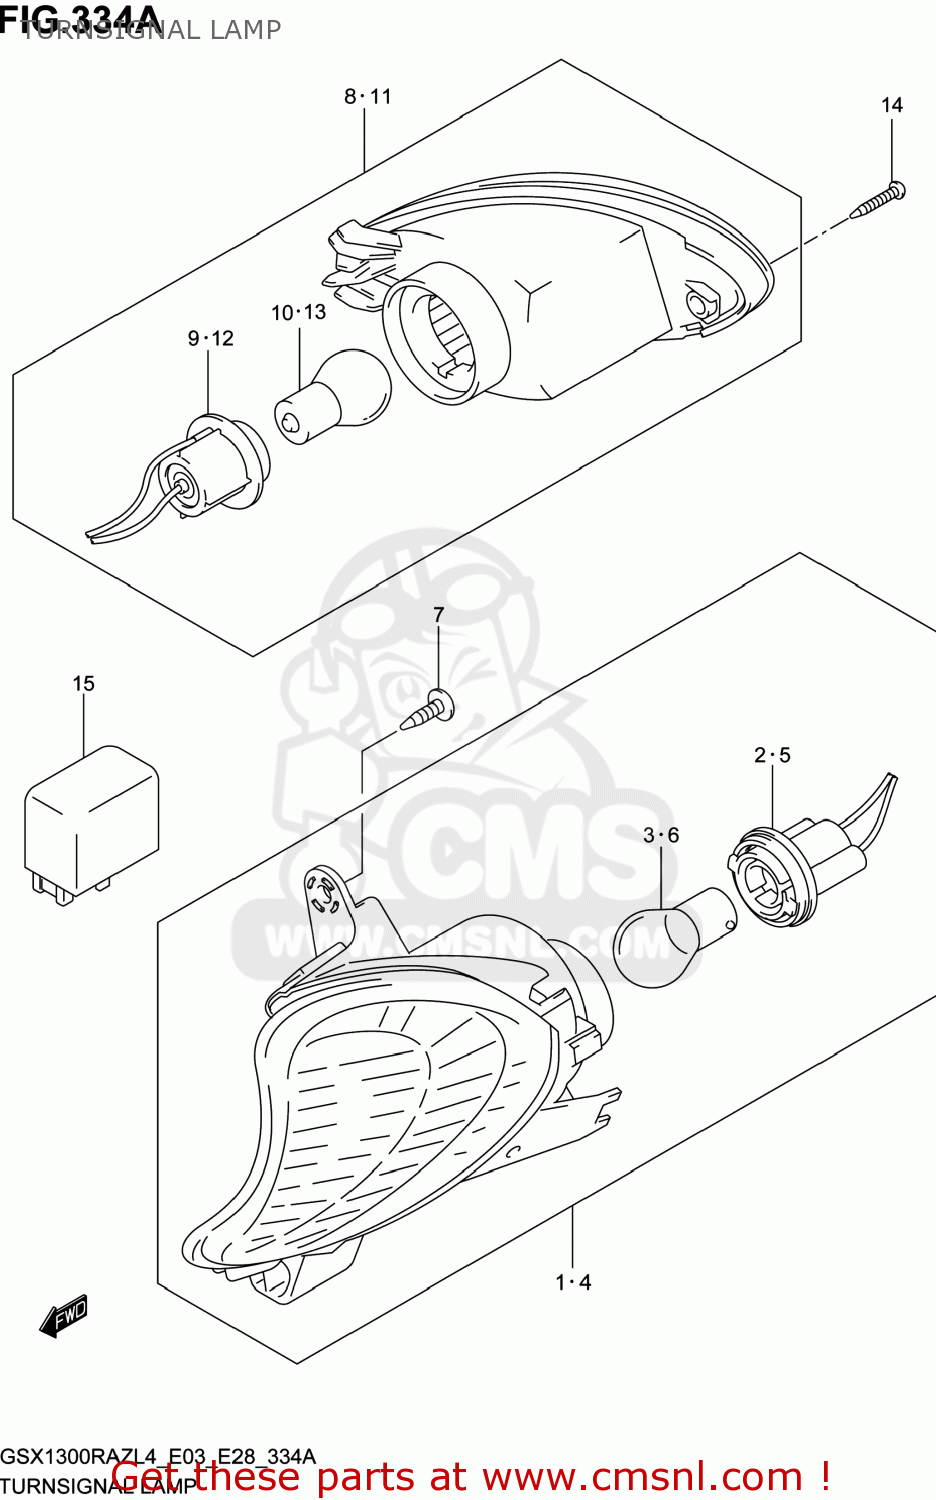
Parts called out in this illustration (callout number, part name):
1	LAMP ASSY,FR TURN SIGNAL,R
2	SOCKET & CORD,R
3	BULB(12V21W,AMBER)
4	LAMP ASSY,FR TURN SIGNAL,L
5	SOCKET & CORD,L
6	BULB(12V21W,AMBER)
7	SCREW
8	LAMP ASSY,RR TURNSIGNAL,R
9	SOCKET & CORD,R
10	BULB(12V21W,AMBER)
11	LAMP ASSY,RR TURNSIGNAL,L
12	SOCKET & CORD,L
13	BULB(12V21W,AMBER)
14	SCREW(4X20)
15	RELAY ASSY,TURNSIGNAL LAMP
